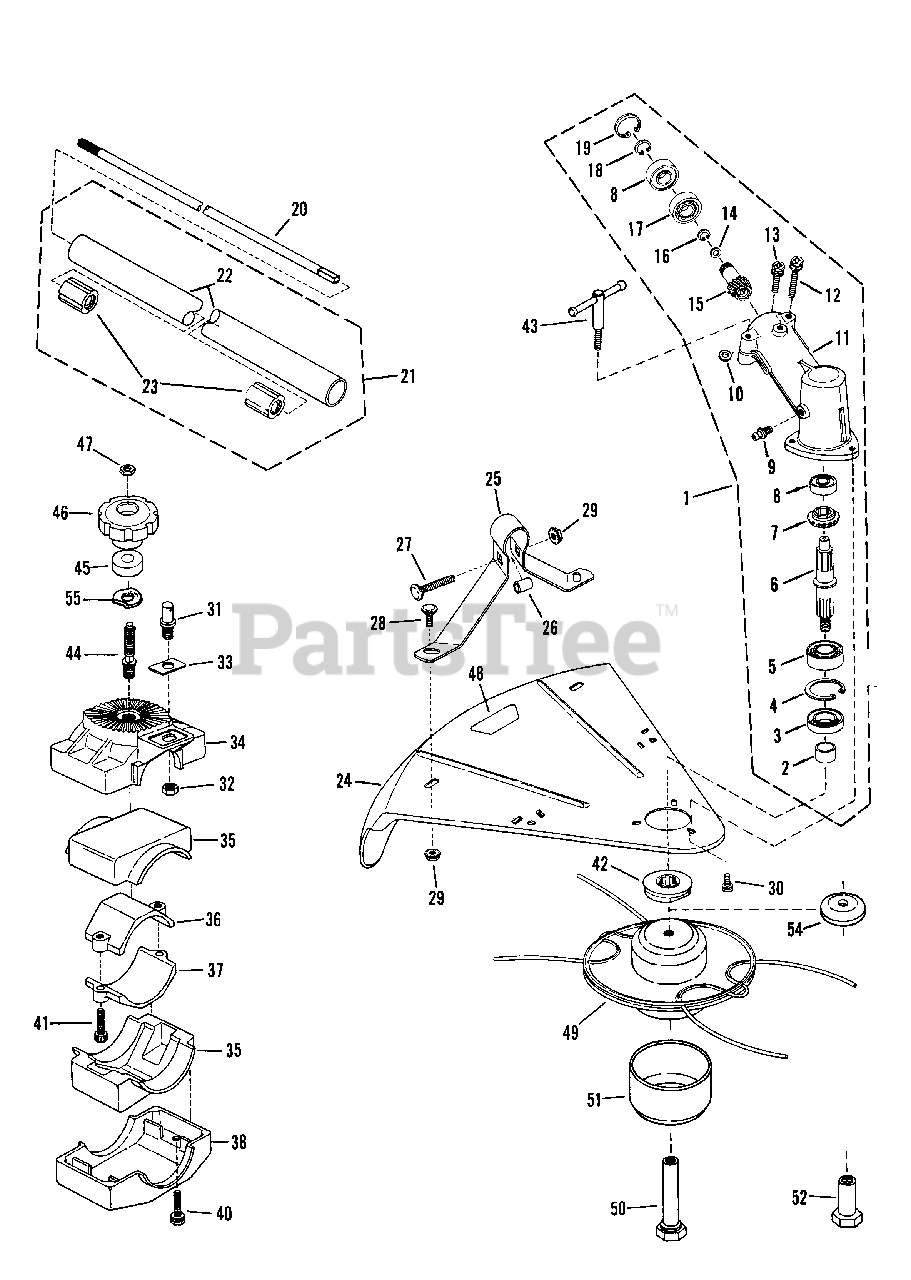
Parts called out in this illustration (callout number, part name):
1	ASSEMBLY, Gear Head
2	SLEEVE, Spline
3	SEAL, Oil
4	RING, Snap 35mm
5	BEARING
6	SHAFT, Spline
7	GEAR, Bevel
8	BEARING
9	FITTING, Lube
11	CASE, Gear
12	BOLT, M5 x 25mm Hex Head
13	BOLT, M5 x 12mm Hex Head
14	WASHER, Flat
15	PINION, Bevel
16	RING, Snap 10mm
17	BEARING
18	RING, Snap 10mm
19	RING, Snap 26mm
20	SHAFT, 1/4 Drive
21	ASSEMBLY, Tube & Bushing
22	TUBE, Main
23	BUSHING
24	SHIELD, Steel
25	BRACE, Shield
26	SPACER, 7/16x11/16
27	BOLT, 5/16-18x1-1/2 Short Neck Carriage
28	BOLT, 5/16-18x1/2 Short Neck Carriage
29	NUT, 5/16-18 Hex Flange Lock
30	SCREW, M5x10mm Hex
31	PIN, Guide
32	NUT, 3/8-24 Hex Flange Lock
33	PLATE, Mounting Pin
34	JOINT "D", Handle
35	RUBBER, Vibro
36	CLAMP "A", Tube
37	CLAMP "B", Tube
38	JOINT "C", Handle
39	JOINT "D", Handle
40	SCREW, M6 x 30mm, Cross Hex Head
41	SCREW, M5x20mm, Socket Hex Head
42	HOLDER "A"
43	T-BOLT, M5
44	BOLT, Latch
45	SPACER, Knob
46	KNOB, Torque
47	NUT, Self-Threader
48	LABEL, Direction
49	HEAD, Fixed Line
50	BOLT, Arbor
51	BALL, Glide
52	ARBOR, Bolt/Blade (Blade Use Only)
53	NUT, M10x1.25 Hex Lock(Left Thread)(Blade Use Only)
54	HOLDER "B"
55	WASHER, Wave
